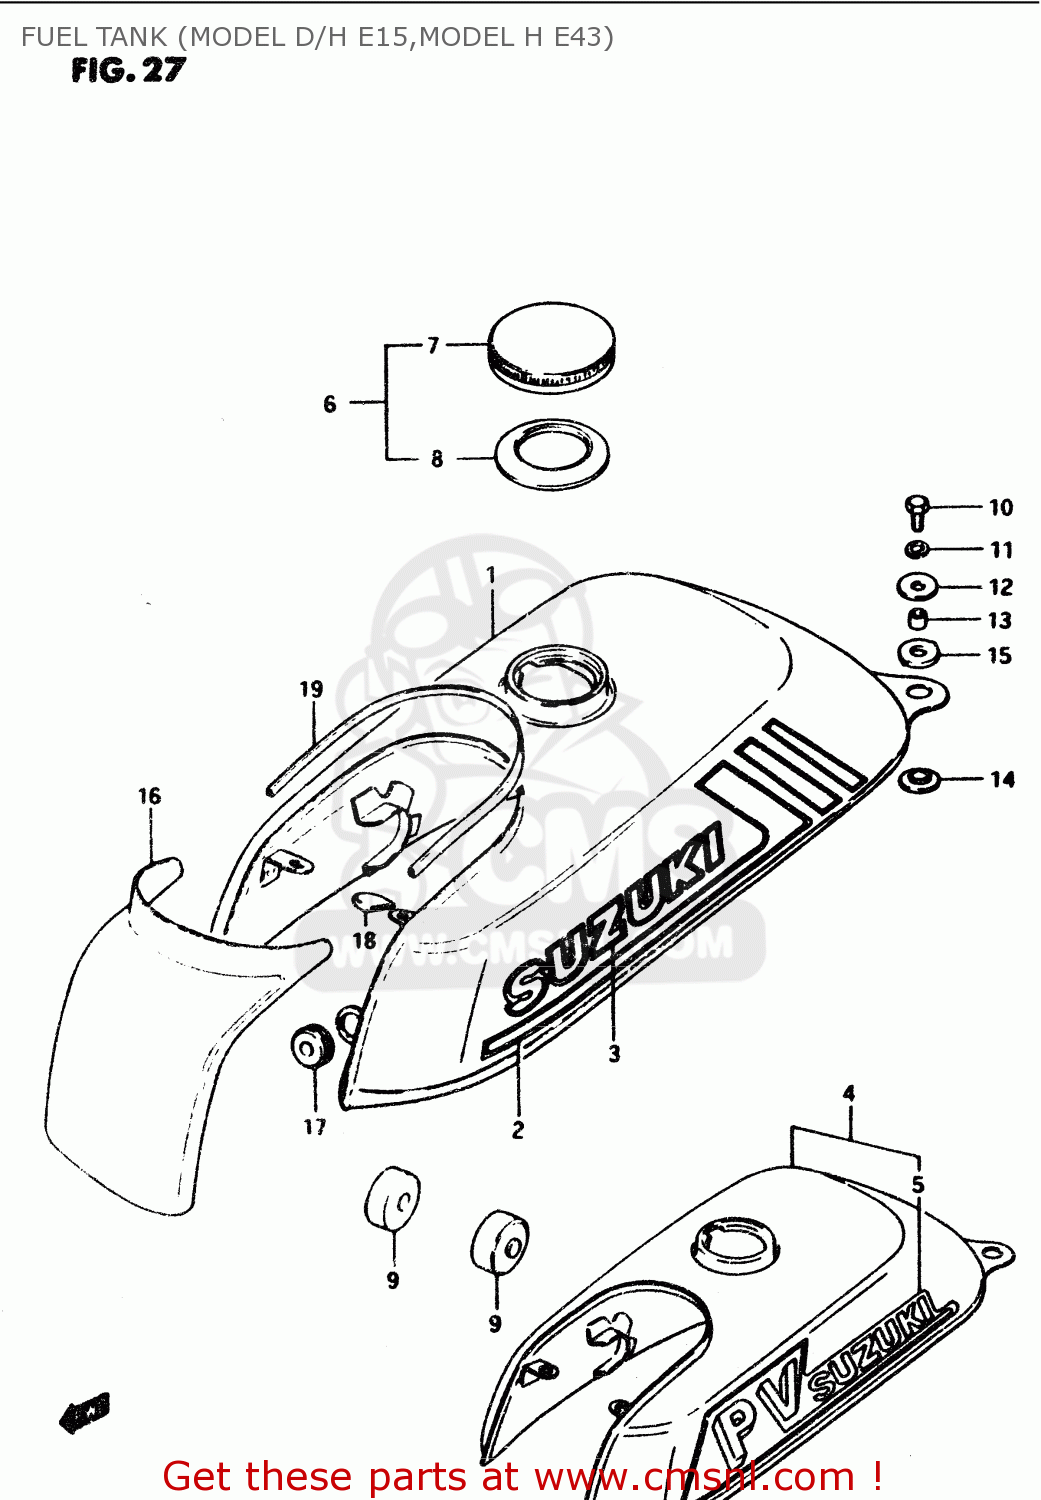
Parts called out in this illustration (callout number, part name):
1	TANK ASSY, FUEL (BLACK)
2	TAPE SET, FUEL TANK
3	EMBLEM
4	TANK ASSY, FUEL (WHITE)
5	TAPE SET, FUEL TANK
6	CAP ASSY,FUEL TANK FILLER
7	CAP,FUEL TANK
8	GASKET (NAS)
9	CUSHION
10	BOLT
11	WASHER,LOCK
12	WASHER (6.5X24X1.6)
13	SPACER (6.8X10X10)
14	CUSHION
15	CUSHION
16	COVER,FUEL TANK FR
17	CUSHION
18	CUSHION
19	MOLDING
